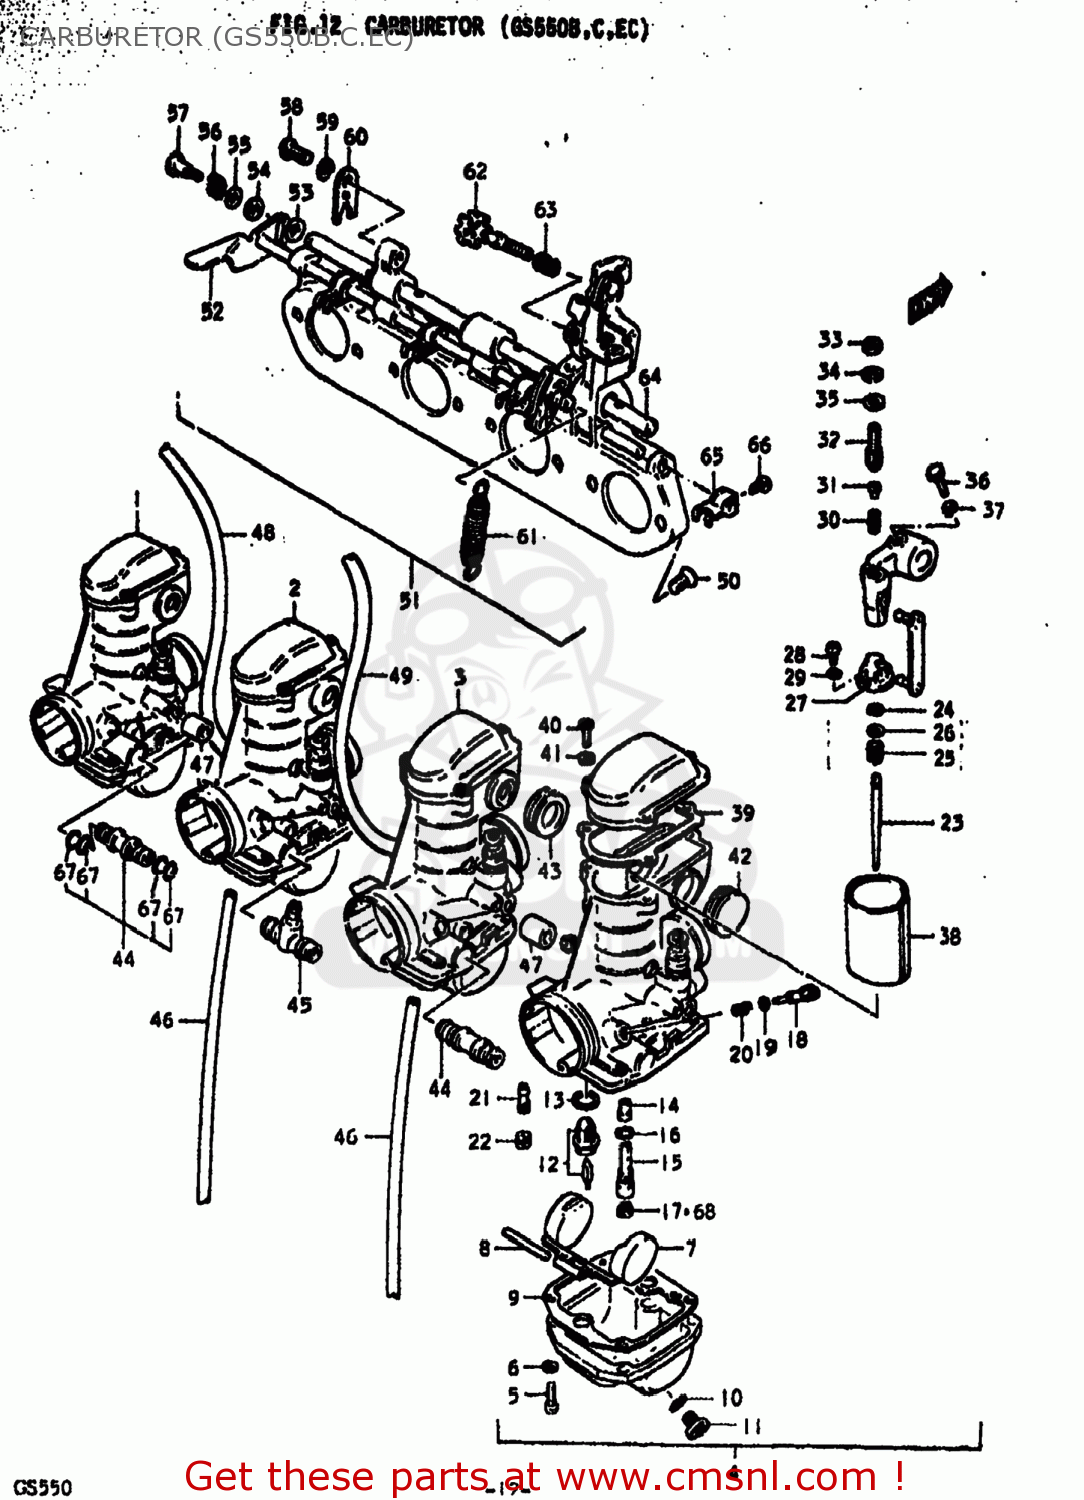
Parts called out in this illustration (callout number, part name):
1	CARBURETOR ASSEMBLY
2	CARBURETOR ASSEMBLY
3	CARBURETOR ASSEMBLY
4	CARBURETOR ASSEMBLY
5	SCREW
6	LOCK WASHER
7	FLOAT
8	PIN,FLOAT
9	GASKET,FLOAT CHAMBER (NAS)
10	O RING
11	SCREW
12	VALVE ASSEMBLY,NEEDLE
13	GASKET,VALVE SEAT (NAS)
14	JET,NEEDLE
15	PIPE,BLEEDER
16	O RING
17	JET
18	SCREW,PILOT AIR
19	O RING
20	SPRING
21	JET
22	JET,AIR(50)
23	NEEDLE JET
24	CLIP
25	SPRING
26	WASHER,JET NEEDLE
27	CONNECTOR
28	SCREW
29	LOCK WASHER
30	SPRING
31	PIN,CARBURETOR
32	SCREW
33	NUT
34	LOCK WASHER
35	WASHER
36	BOLT
37	LOCK WASHER
38	VALVE,THROTTLE
39	GASKET (NAS)
40	SCREW
41	LOCK WASHER
42	PIPE,DELIVERY
43	SEAL
44	NIPPLE
45	NIPPLE
46	HOSE
47	HOSE
48	HOSE
49	HOSE
50	SCREW
51	CARBURETOR ASSEMBLY
52	SHAFT,STARTER
53	WASHER,STARTER SHAFT
54	WASHER
55	WASHER,STARTER SHAFT
56	SPRING
57	SCREW,STARTER LEVER
58	SCREW
59	LOCK WASHER
60	GASKET
61	SPRING,THROTTLE VALVE
62	ADJUSTER
63	SPRING,THROTTLE SCREW
64	SHAFT ASSEMBLY
65	LEVER, STARTER
66	SCREW
67	O-RING
68	JET
